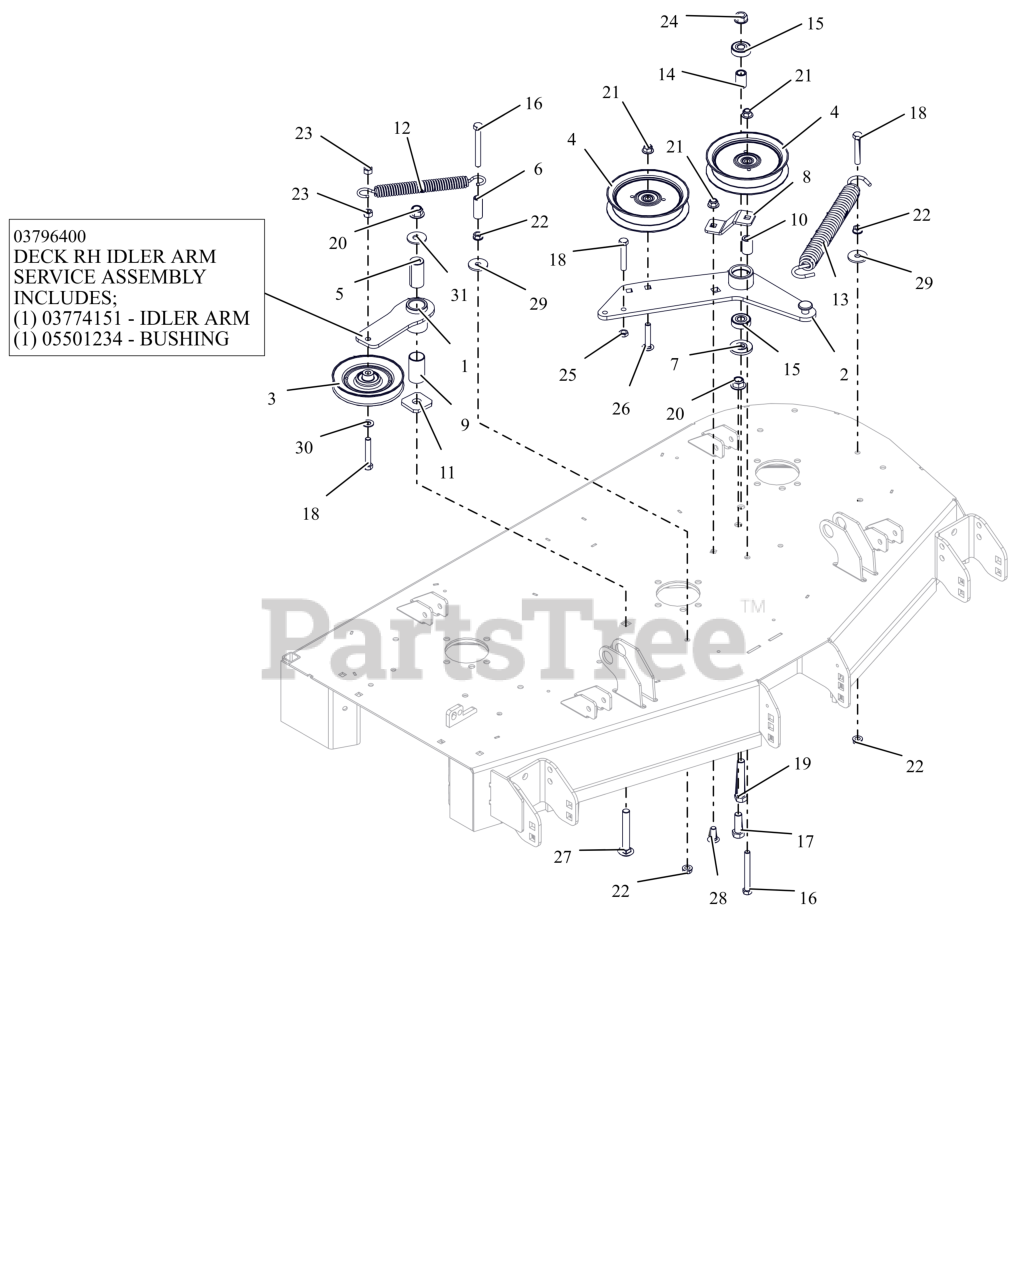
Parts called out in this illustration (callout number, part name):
1	WMT, IDLER ARM - BLACK
1	ASM, IDLER ARM (DECK)
2	DECK PTO IDLER ARM WLDMT - BLK
3	IDLER, V-5.00"
4	IDLER, FLAT 5.00"
5	BSHG, SPCR .502X.997X2.03 PM
6	SPACER, .375IDX.625ODX1.66 PM
7	SPACER, IDLER ARM
8	PTO FIXED IDLER MTG BRKT-ORG
9	BSHG, 1.00X1.125X1.937
10	BUSHING, SLV .380X.750X1.190
11	WSHR-FLT .640X1.75X.250
12	SPRING, EXTENSION
13	SPRING, EXTENSION
14	SPACER .510 X .75 X 1.1485
15	BRG-BALL .500X1.38X.437
16	BLT, HEX .38-16X3.25 G5 ZCC
17	BLT,HEX .50-13X1.50 G5 ZCC
18	BLT,HEX .38-16X2.25 G5 ZCC
19	BLT, HEX .50-13X3.00 G5 ZCC
20	NUT,NYL-FLG .50-13 GF ZCC
21	NUT,NYL-FLG .38-16 GF ZCC
22	NUT, SPNLK-FLG .38-16 G5 ZCC
23	NUT-LK-CTR .38-16 ZC120
24	NUT-LK-CTR-FLG .500-13 GG ZCC
25	NUT-JAM .375-16 G2 ZCC
26	BLT,RHSSN.375-16X2.00 G5 ZCC
27	BLT, RHSN .50-13X3.50 G5 ZCC
28	BLT,RHSSN .38-16X1.00 G5 ZCC
29	WSHR,FLT .406X1.375X.135 ZCC
30	WSHR,FLT .406X.812X.065 ZCC
31	WSHR,FLT .563X1.375X.109 ZCC
